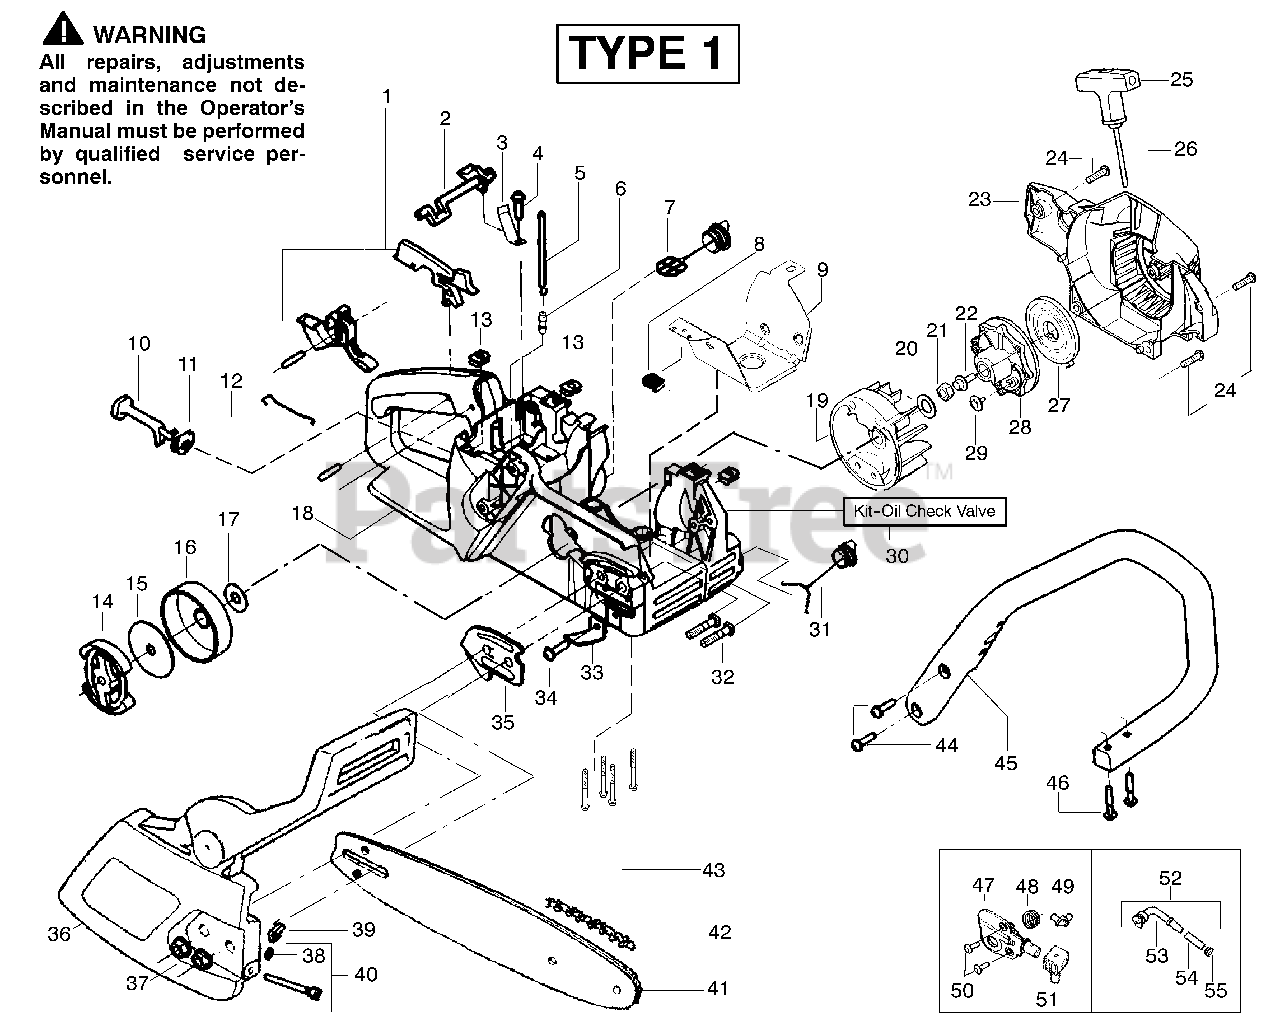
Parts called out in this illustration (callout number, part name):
1	Kit-Trigger & Lockout
2	Lever-Switch
3	Spring-Switch
5	Kit-Fuel Line
6	Fitting - Fuel line
7	Assy-Fuel Cap w/ret.
8	Clip - "U"
9	Shield - Heat
10	Lever-Choke
11	Grommet-Choke lever
12	Wire-Throttle
13	Nut-Speed
14	Assy.-Clutch
15	Washer-Clutch
16	Assy-Drum W/brg.
17	Washer - Thrust
18	Assy.-Chassis
19	Assy-Flywheel
20	Washer-Flywheel
21	Nut-Flywheel
23	Housing-Fan
25	Handle-Starter
26	Kit-Rope
27	Spring-Starter
28	Pulley-Starter
30	Kit-Oil Check Valve
31	Assy-Oil Cap
32	Bolt - Bar
33	Chain Catcher
35	Plate-Bar Mounting
36	Assy.-Chain Brake
37	Nut-Bar Mounting
38	Retainer-Bar Adjust
39	Pin-Bar Adjust
40	Kit-Bar Adjust
42	Chain-14"
45	Handle-Front
47	Kit-Oil Pump
48	Gear-Worm Spring
49	Elbow-Oil Pickup
51	Block-Seal
52	Assy-Oil-Pickup
53	Pickup-Oiler
54	Filter-Oil
55	Plug-Oil Filter
